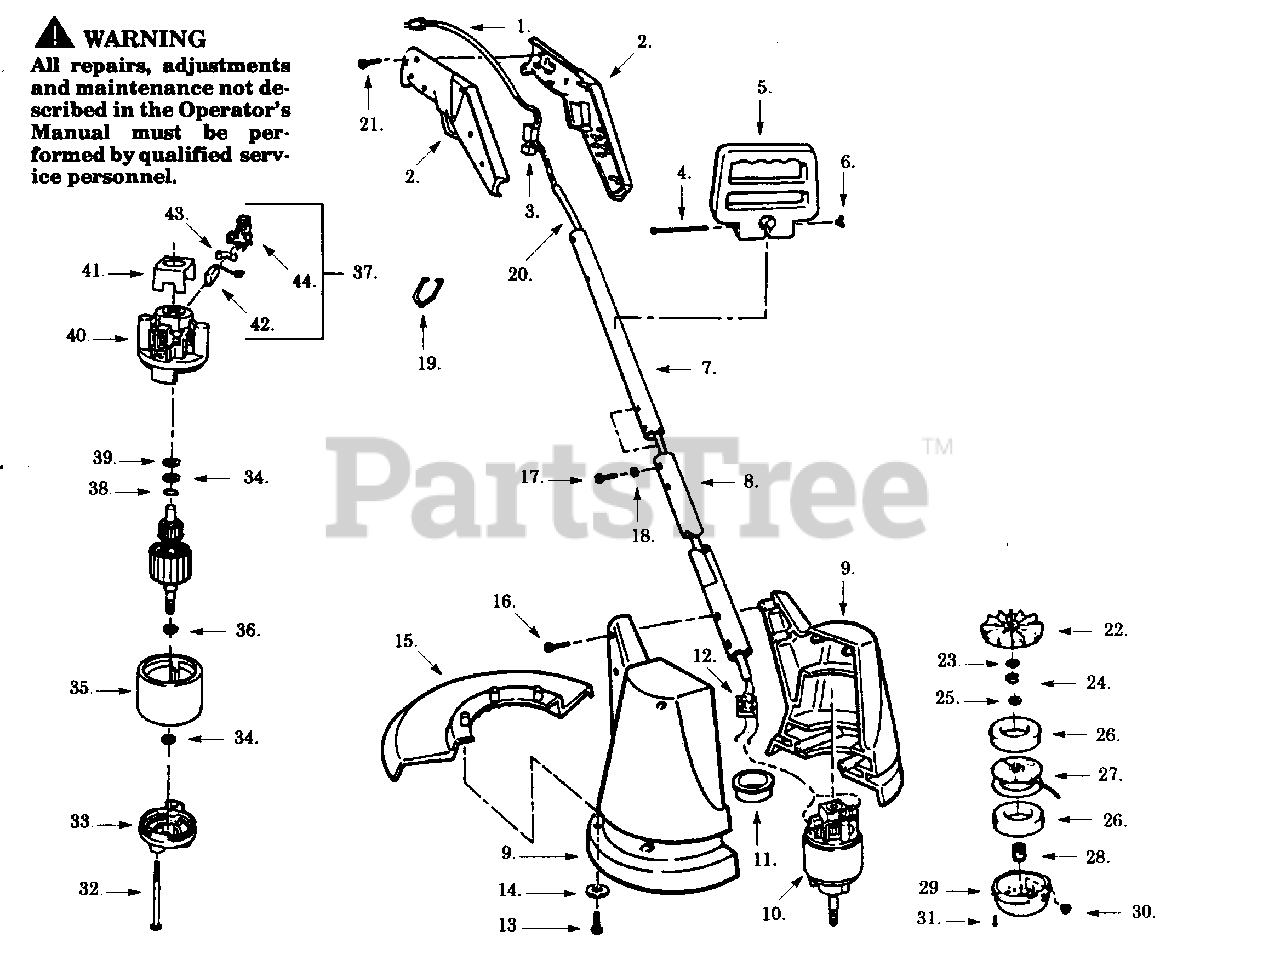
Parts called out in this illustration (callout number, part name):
1	Power Cord
2	R.H./L.H. Handle
3	Trigger Switch
5	Side Handle
6	Wing Nut
7	Upper Tube
8	Lower Tube
9	R.H./L.H. Housing
11	Air Baffle
12	P.C. Bridge Kit
15	Line Cutter Guard
18	Lockwasher
20	Harness Ass'y.
22	Rear Plate
24	Retaining Ring
25	Wire Retaining Ring
26	Foam Pad
27	Spool & Line
29	Hub Ass'y.
31	Cotter Pin
33	Endbell Ass'y. (Drive)
35	Field Ass'y.
36	Retaining Ring
37	Brush Kit (Inc.42,43,44)
38	Retaining Ring
40	Endbell Ass'y. (Brush)
41	Insulator
43	Brush Spring
44	Brush Holder
